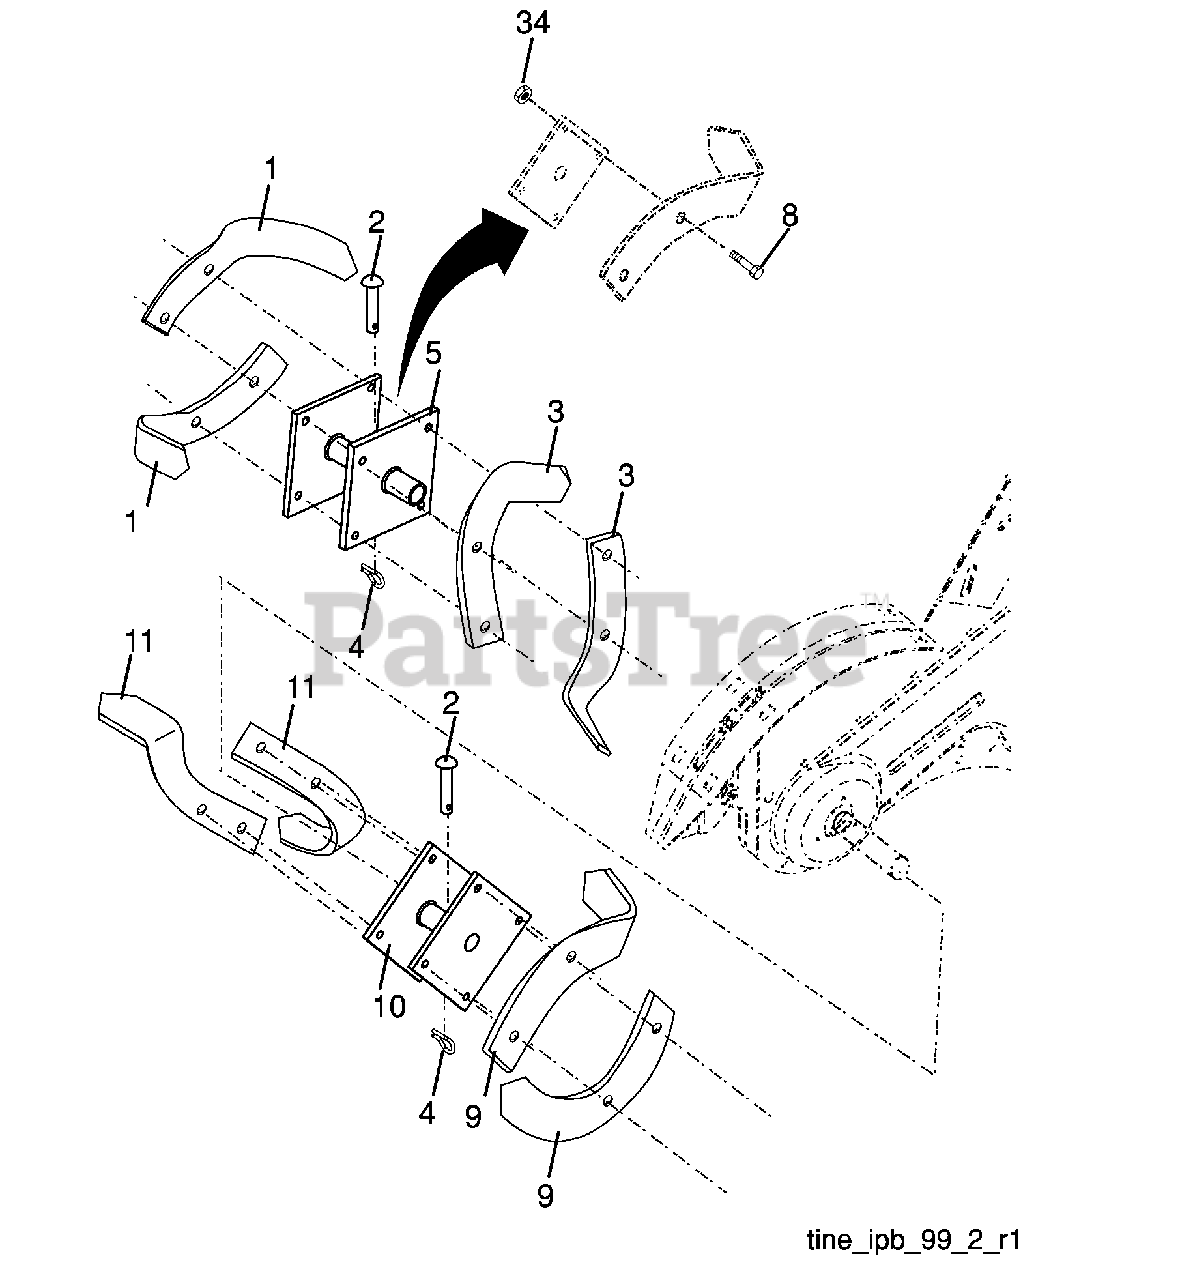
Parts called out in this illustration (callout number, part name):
1	Tine, Outer, L.H.
2	Clevis Pin
3	Tine, Inner, L.H.
4	Retainer, Spring Zinc
5	Assembly, Hub and Plate, L.H.
8	Bolt, Hex 3/8-24 x 1
9	Tine, Outer, R.H.
10	Assembly, Hub and Plate, R.H.
11	Tine, Inner, R.H.
34	Nut Crownlock 3/8-24
